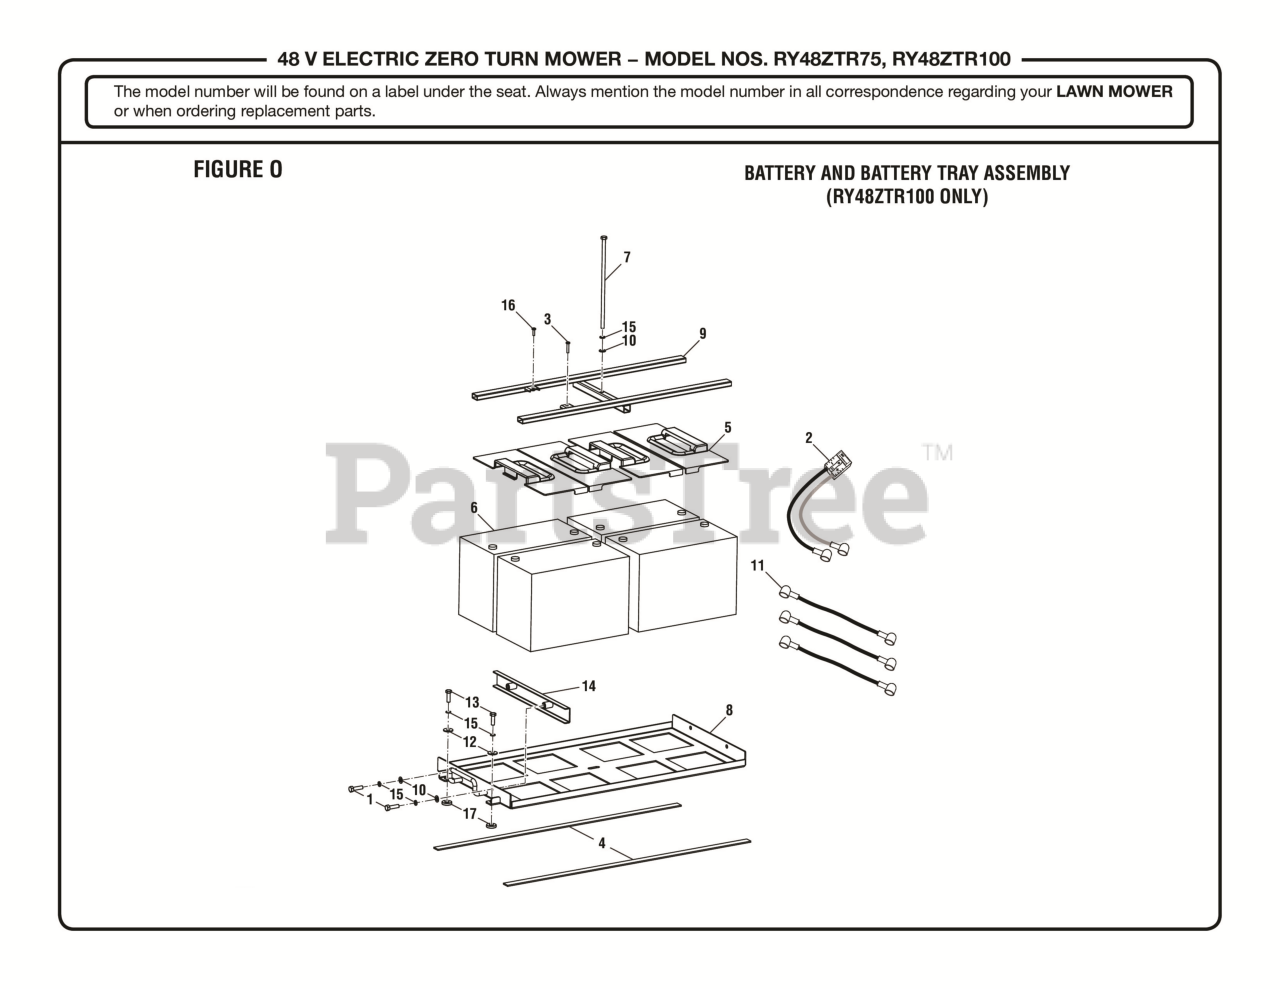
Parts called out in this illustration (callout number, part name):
1	Bolt (M8 x 25 mm)
2	Battery Cable 2, ZTR
3	Screw (M5 x 25 mm)
4	Battery Tray Slider
5	Battery Shield, ZTR
6	Battery (LPC12-100, RY48111)
7	Hex Bolt (M8 x 240 mm)
8	Battery Tray
9	Battery Tie Down
10	Washer (OD16 x ID8.4 x 1.6t)
11	Battery Cable w/Covers (Red and Black, 120 mm)
12	Washer (OD 24 x ID8.4 x 2t)
13	Bolt (M8 x 25 mm, Hex Hd.)
14	Battery Holder Bracket
15	Lock Washer (OD9.8 x ID8.5 x 5t)
16	SCREW,PPHMS, M5 X 0.8 X 16 - STEEL,
17	Metal Bushing
